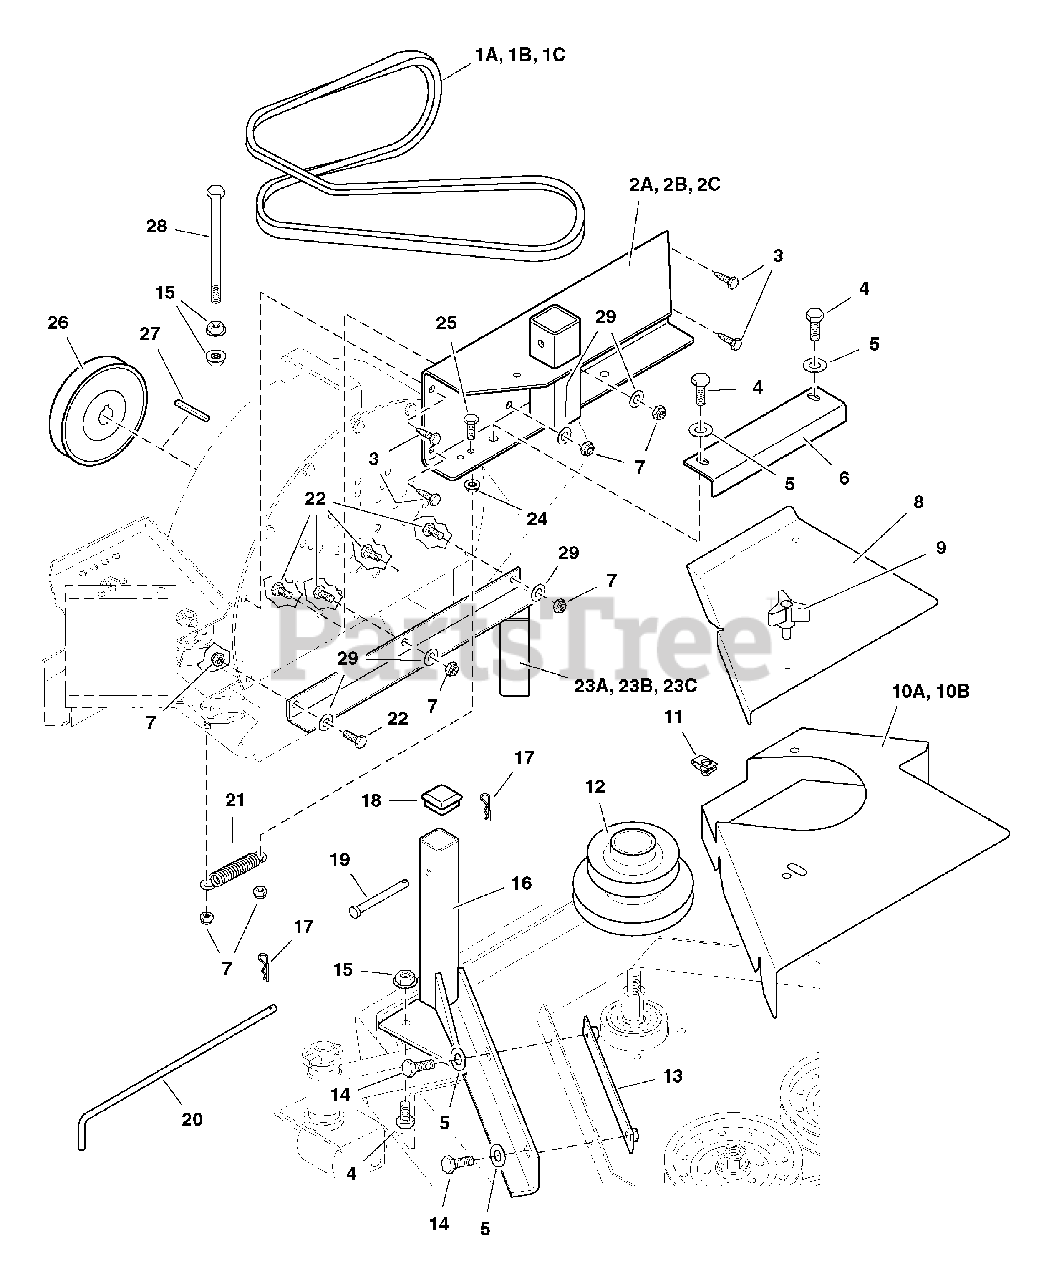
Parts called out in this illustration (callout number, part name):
1A	BELT (31207)(31207-61)
1B	BELT (31207-61A)
1C	BELT (31207-61B)
2A	BLOWER MOUNT (31207)(31207-61)
2B	BLOWER MOUNT (31207-61A)
2C	BLOWER MOUNT (31207-61B)
3	SCREW, Self-tapping, 5/16-18 x 3/4
4	CAPSCREW, Hex Hd, 3/8-16 x 1
5	WASHER, 3/8
6	BOTTOM BRACE
7	NUT, Hex, Nylon Lock, 5/16-18
8	BELT SHIELD
10A	DECK GUARD (31207)(31207-61)
10B	DECK GUARD (31207-61A)(31207-61B)
11	BODY CLIP, 5/16-18
12	SPINDLE PULLEY
13	INSIDE SUPPORT
14	CAPSCREW, Hex Hd, 3/8-16 x 1-1/4
15	NUT, Hex, Serrated Flange, 3/8-16
16	BLOWER DECK SUPPORT
17	HAIRPIN CLIP
18	CAP
19	CLEVIS PIN, 3/8 x 4
20	QUICK CONNECT ROD
22	CAPSCREW, Hex Hd, 5/16-18 x 3/4
23A	BOTTOM ADAPTER (31207)(31207-61)
23B	BOTTOM ADAPTER (31207-61A)
23C	BOTTOM ADAPTER (31207-61B)
24	NUT, Hex, Serrated Flange, 5/16-18
25	CAPSCREW, Hex Hd, 5/16-18 x 1-1/4
26	BLOWER DRIVE PULLEY
27	KEY, 1/4 Sq. x 1-1/2
28	CAPSCREW, Hex Hd, 3/8-16 x 6
29	WASHER, 5/16
